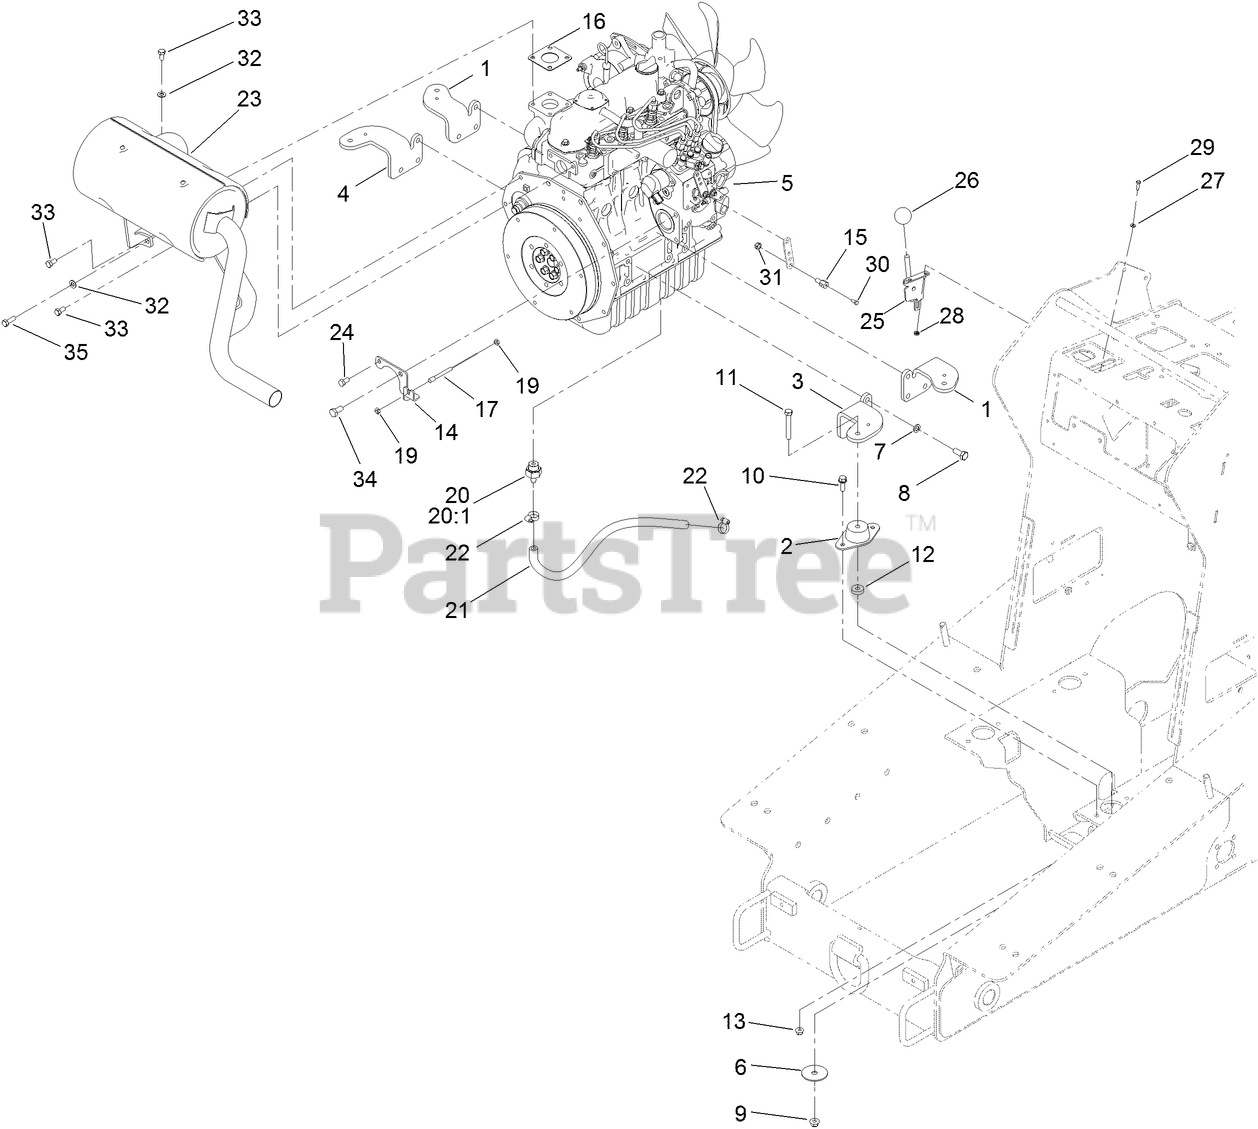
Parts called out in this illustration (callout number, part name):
1	MOUNT-ENGINE
2	MOUNT-ENGINE
3	MOUNT-ENGINE LH
4	MOUNT-ENGINE, RH
5	ENGINE ASM
6	WASHER-SNUBBING
7	WASHER-LOCK
8	SCREW-HH
9	NUT-HF, NI
10	SCREW-HHF
11	SCREW-HH
12	SPACER
13	NUT-HF, NI
14	BRACKET-THROTTLE
15	SWIVEL-THROTTLE
16	GASKET-MUFFLER
17	CABLE-THROTTLE
19	NUT-JAM
20	FITTING-HOSE
20:1	GASKET
21	HOSE-OVERFLOW, RADIATOR
22	CLAMP-HOSE
23	MUFFLER-DIESEL
24	SCREW-HH
25	LEVER-CONTROL
27	WASHER-FLAT
28	NUT-KEPS
30	SCREW-HH
31	NUT-LOCK, NI
32	WASHER-PLAIN
33	BOLT
34	SCREW-CAP
